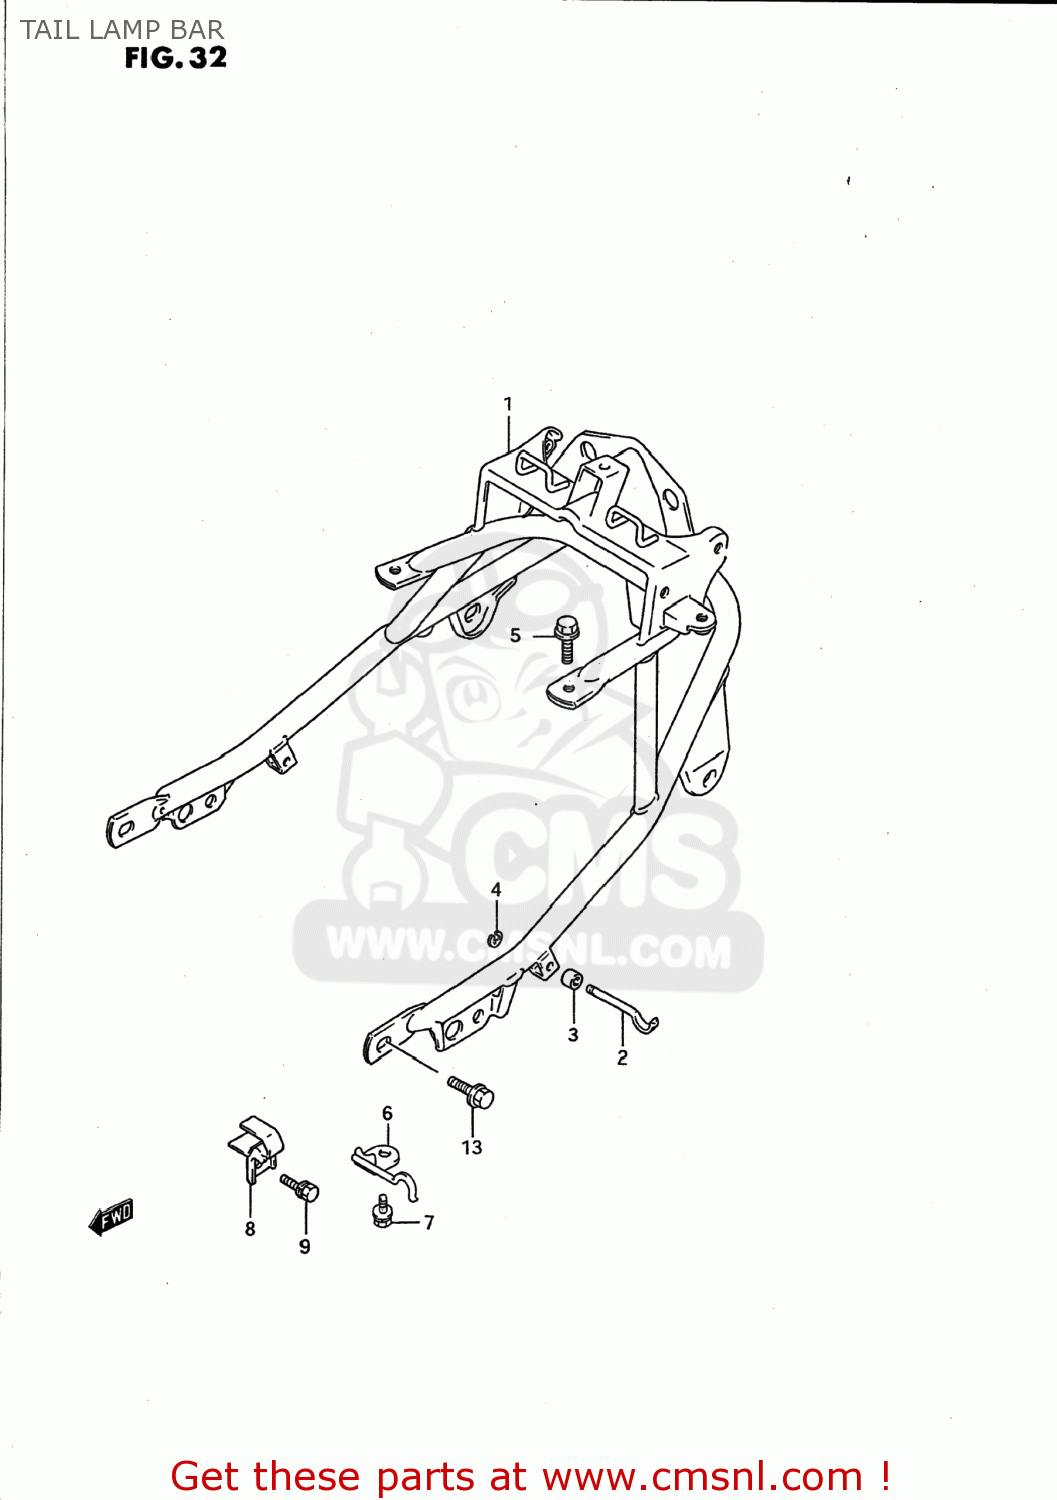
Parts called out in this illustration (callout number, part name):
1	BAR,TAIL LAMP BRACKET
2	ROD,GRIP
3	SPACER,GRIP ROD
4	E RING
5	BOLT
6	ROD,GRIP,LEFT
7	BOLT
8	HOLDER,HELMET
9	BOLT
